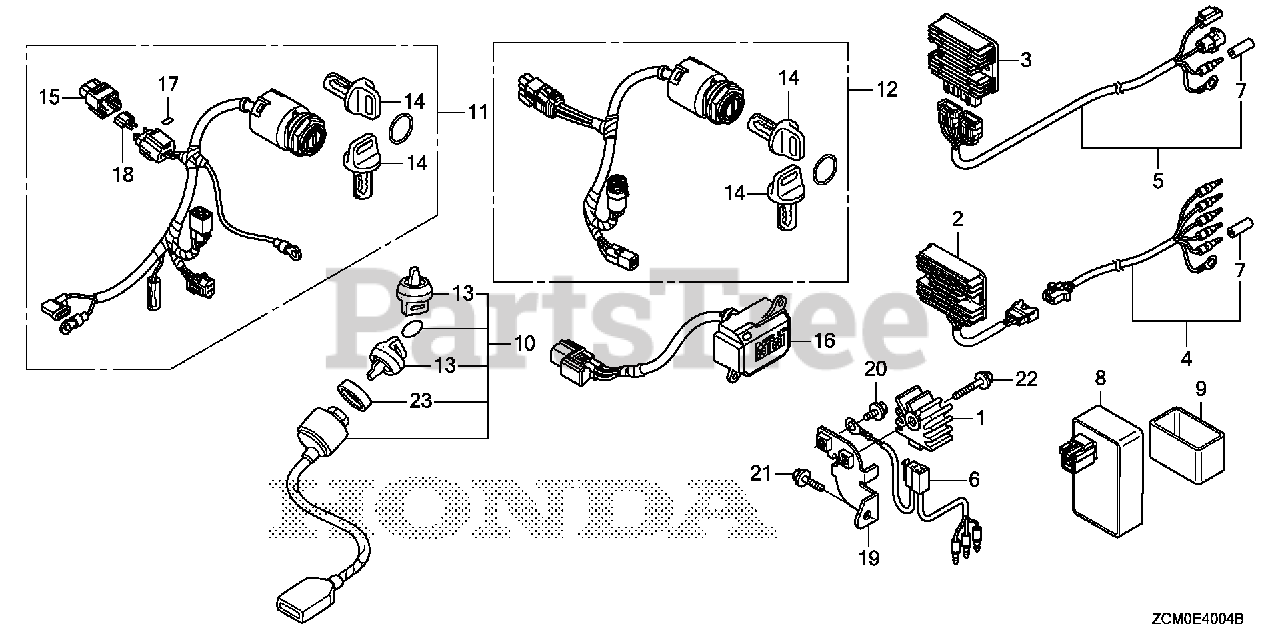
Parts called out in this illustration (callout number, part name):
2	RECTIFIER ASSY., REGULATOR (20A)
4	SUB-WIRE HARNESS ASSY.
7	PLUG, CONNECTOR (OUTER) (ENGINE NO.)
